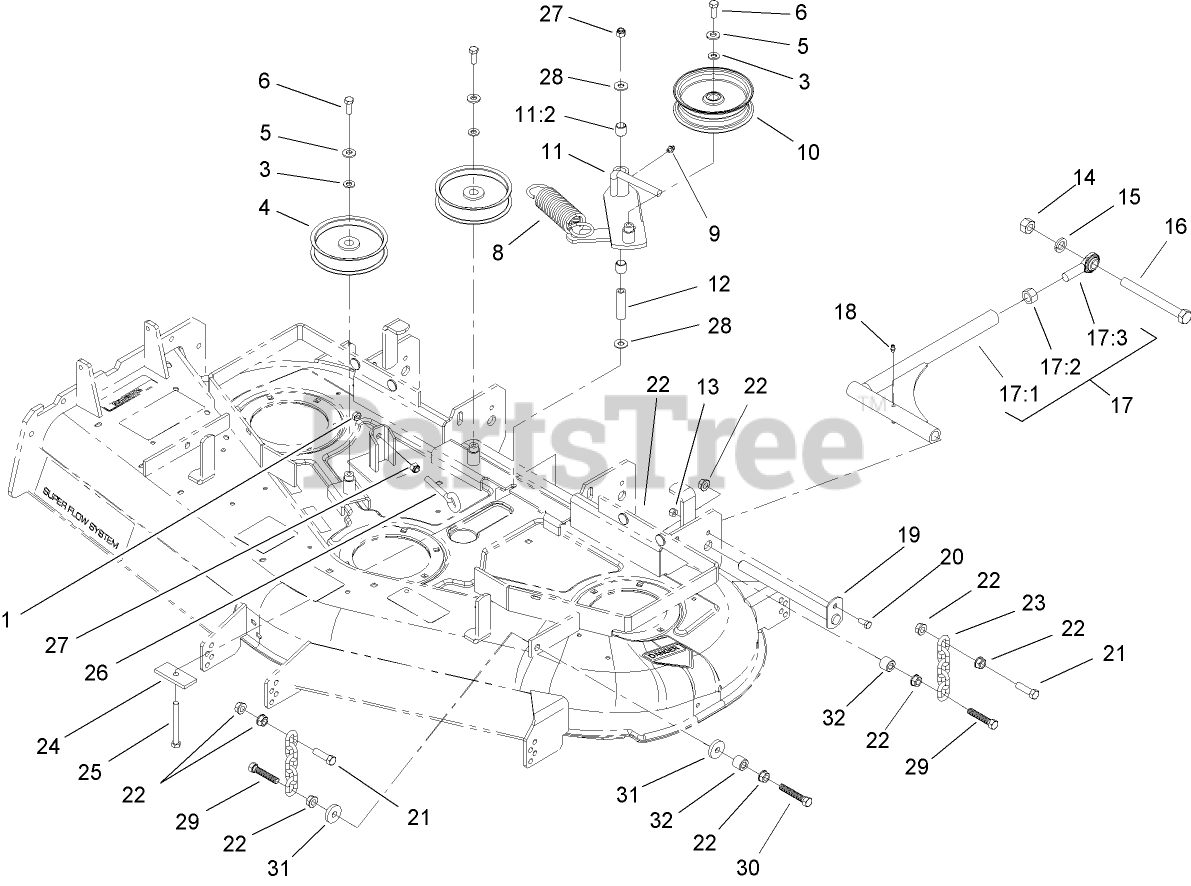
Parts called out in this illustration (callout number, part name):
1	NUT-HEX
3	WASHER-FLAT
4	PULLEY-IDLER
5	WASHER-BELLEVILLE
6	SCREW-HH
8	SPRING-EXTENSION
9	FITTING-GREASE, 90 DEG
10	PULLEY-IDLER, FLAT
11	IDLER ARM ASM
11:2	SLEEVE-BEARING
12	BUSHING-PIVOT, IDLER
13	NUT-LOCK, NI
14	NUT-HEX
15	WASHER-LOCK
17	STRUT ASM
17:1	STRUT
17:2	NUT-HEX
17:3	BALLJOINT-SPHERICAL
18	FITTING-GREASE
19	PIN-STRUT
20	SCREW-HH
21	SCREW-HH
22	NUT-HF
23	CHAIN-LIFT, DECK
24	PLATE-RETAINER, BOLT
25	SCREW-HH
26	BOLT-EYE
27	NUT-LOCK, NI
28	WASHER-HARDENED
29	SCREW HH
30	SCREW HH
31	WASHER
32	SPACER-BEDBAR
